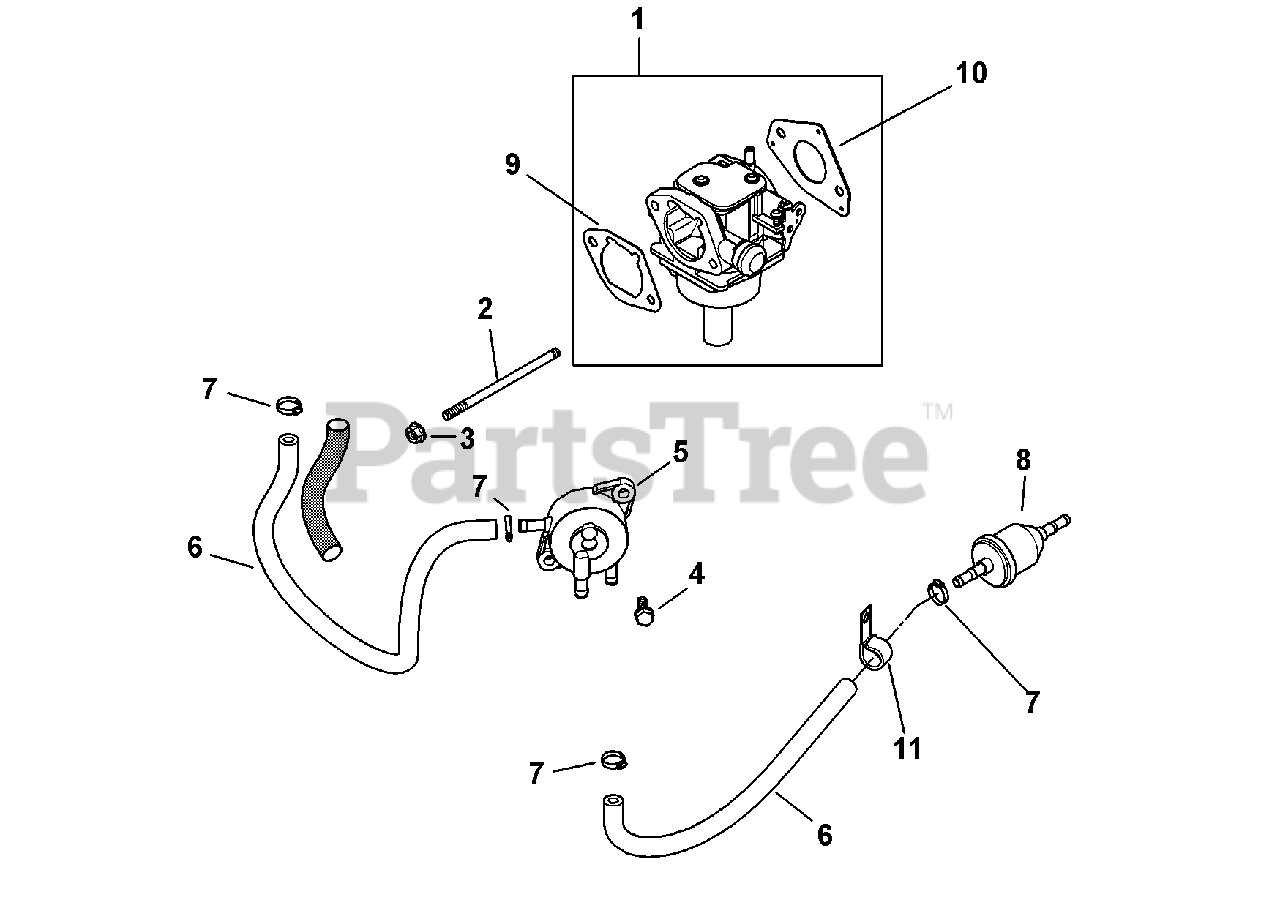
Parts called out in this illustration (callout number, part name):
1	Carburetor Kit
2	Stud, M6 x 1.0 x 106
3	Flange Nut, M6 x 1.0
4	Tap Screw, M6 x 1.7 x 18
7	Hose Clamp, 1/2
9	Air Cleaner Base Gasket
10	Carburetor Gasket
